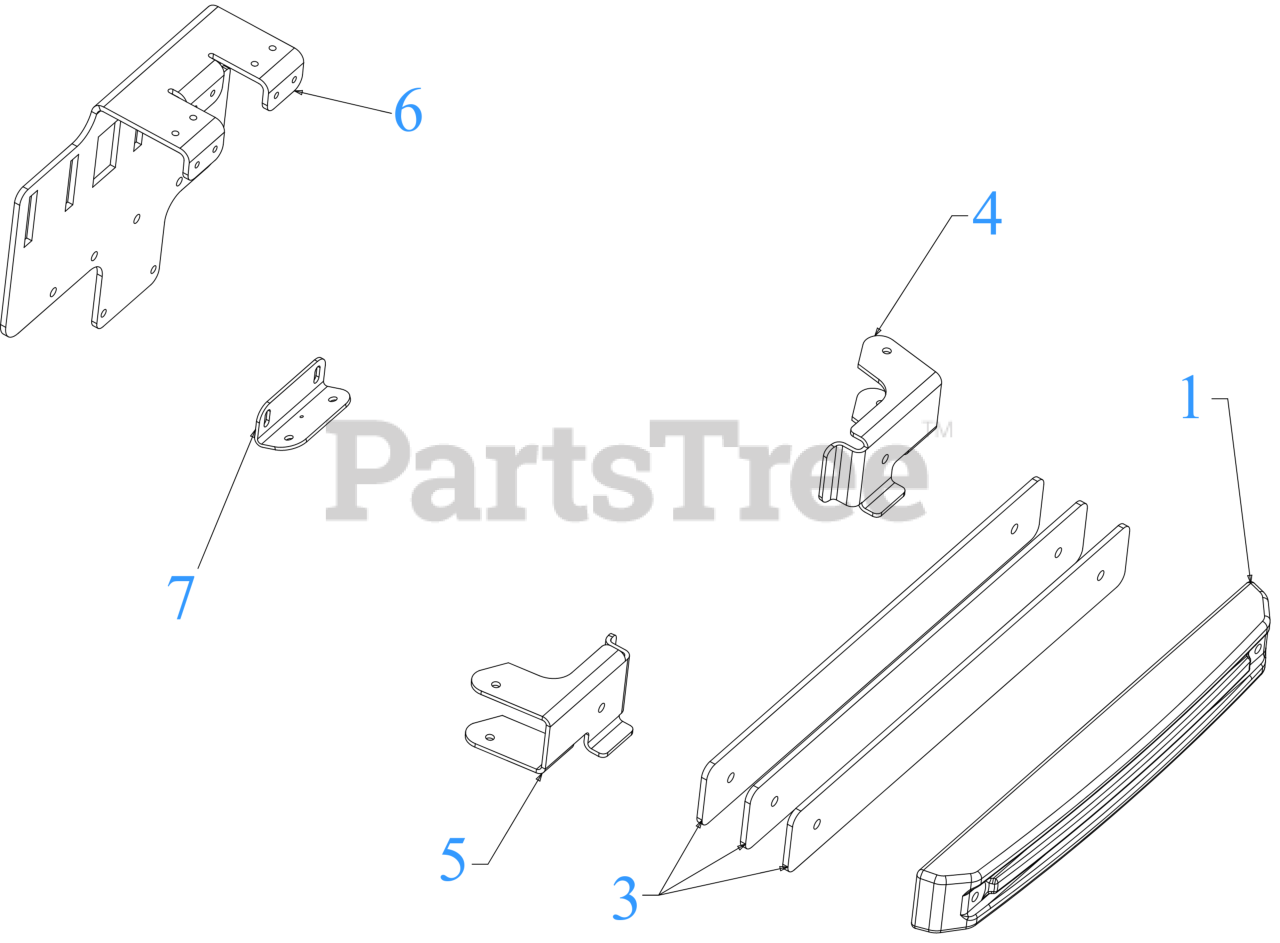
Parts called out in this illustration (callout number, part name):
1	BAGGER WEIGHT
2	BAGGER BRAKET LABEL
3	WEIGHT PLATE
4	WEIGHT HANGER BRACKET (LH)
5	WEIGHT HANGER BRACKET (RH)
6	ADAPTER BRACKET
7	HITCH ADAPTER BRACKET
